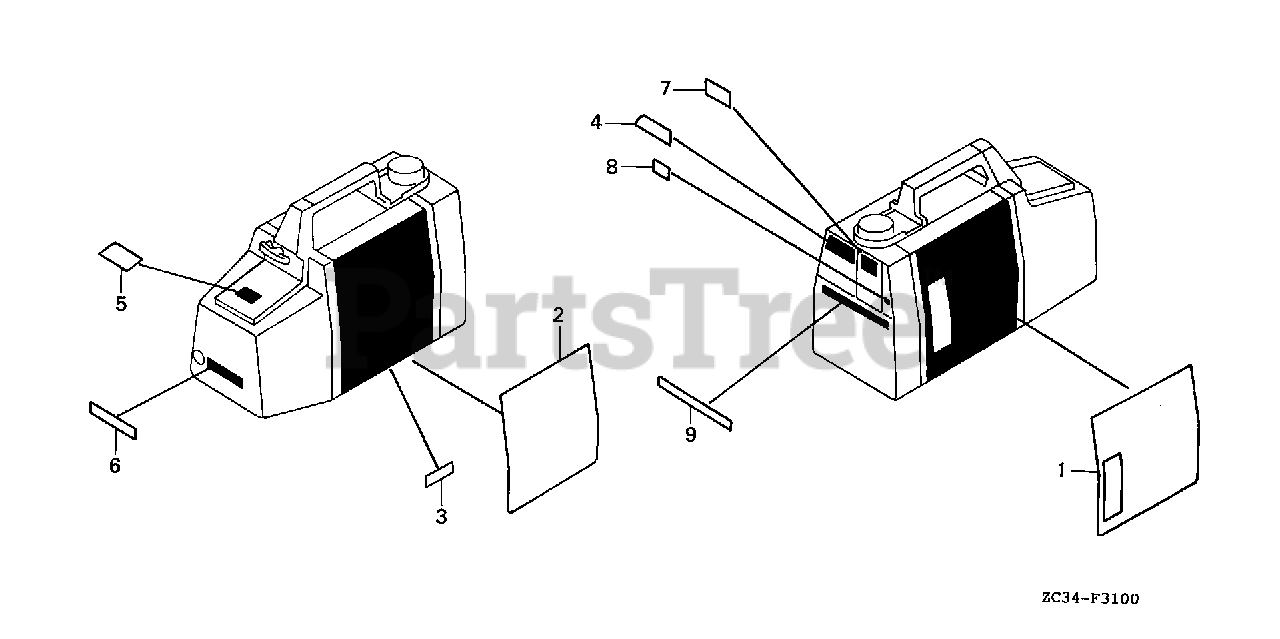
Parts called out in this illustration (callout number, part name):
2	MARK, CAUTION
3	LABEL, RAIN WARNING (ENGLISH)
4	MARK, D.C. CAUTION
5	MARK, AIR CLEANER CAUTION
6	MARK, EX. CAUTION
7	LABEL, A.C. CAUTION
8	MARK, A.C. INDICATION
9	MARK, CIRCUIT BREAKER
